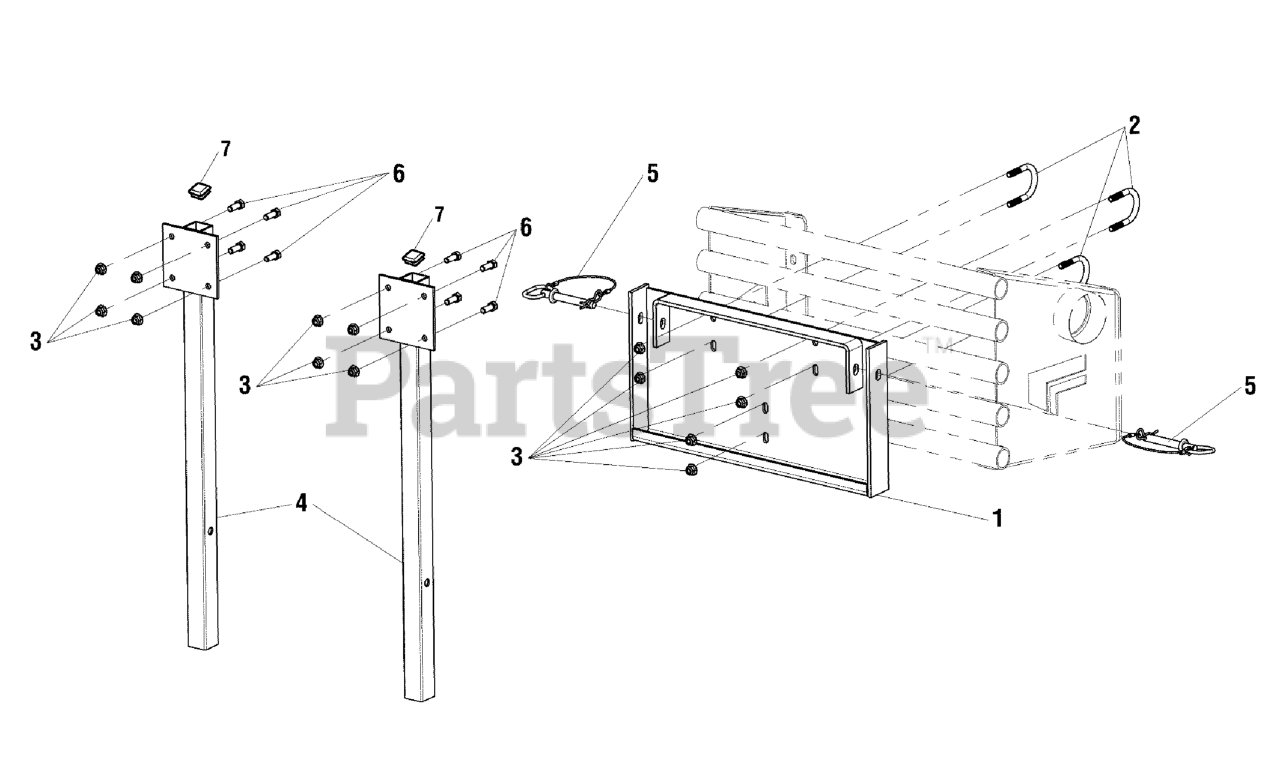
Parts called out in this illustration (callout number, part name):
1	WELD, BAGGER MOUNT, IS3100Z
2	U-BOLT, 3/8" X 1-1/4"
3	NUT, 3/8-16 HEX NYLOCK FLANGE
4	WELD, MOUNT, POST
5	PIN, HITCH, .50 X 3.25 W/ LANYARD
6	BOLT, 3/8-16 X 1" GD5 CZ
7	CAP, PLASTIC, 1-1/2" X 1-1/2
